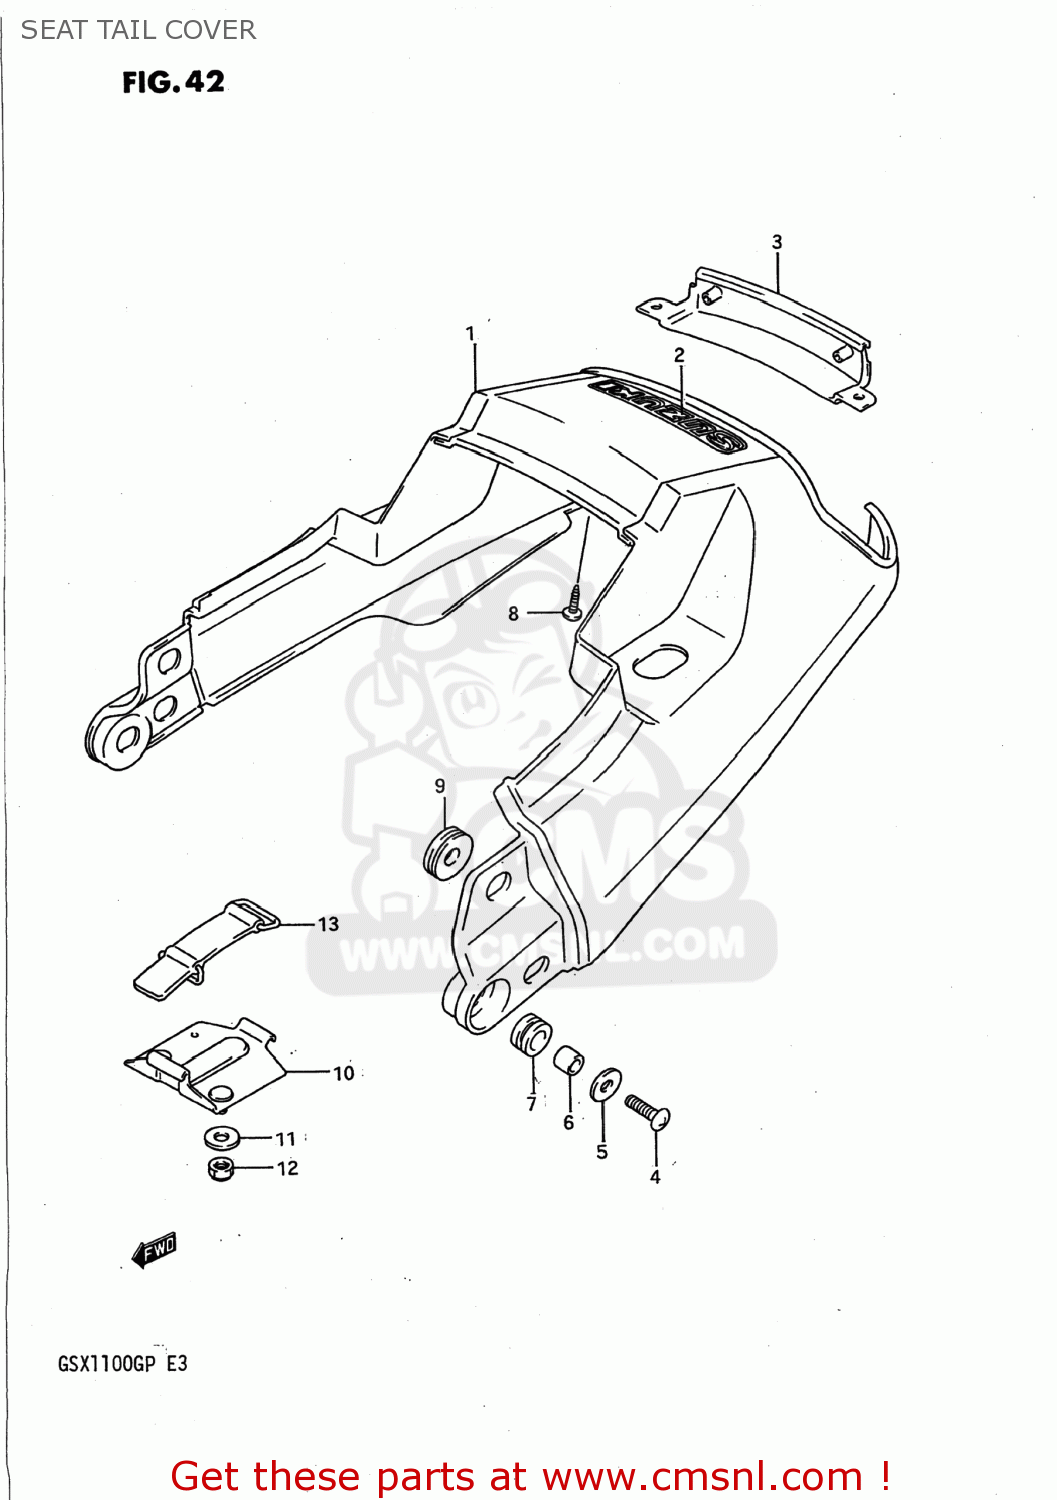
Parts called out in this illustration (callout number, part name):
1	COVER ASSEMBLY,SEAT TAIL
2	EMBLEM
3	COVER,SEAT TAIL,LOWER
4	SCREW, CENTER
5	WASHER(6.5X18X1)
6	SPACER
7	CUSHION
8	SCREW
9	CUSHION
10	HOLDER,TOOL
11	WASHER
12	NUT
13	BAND
